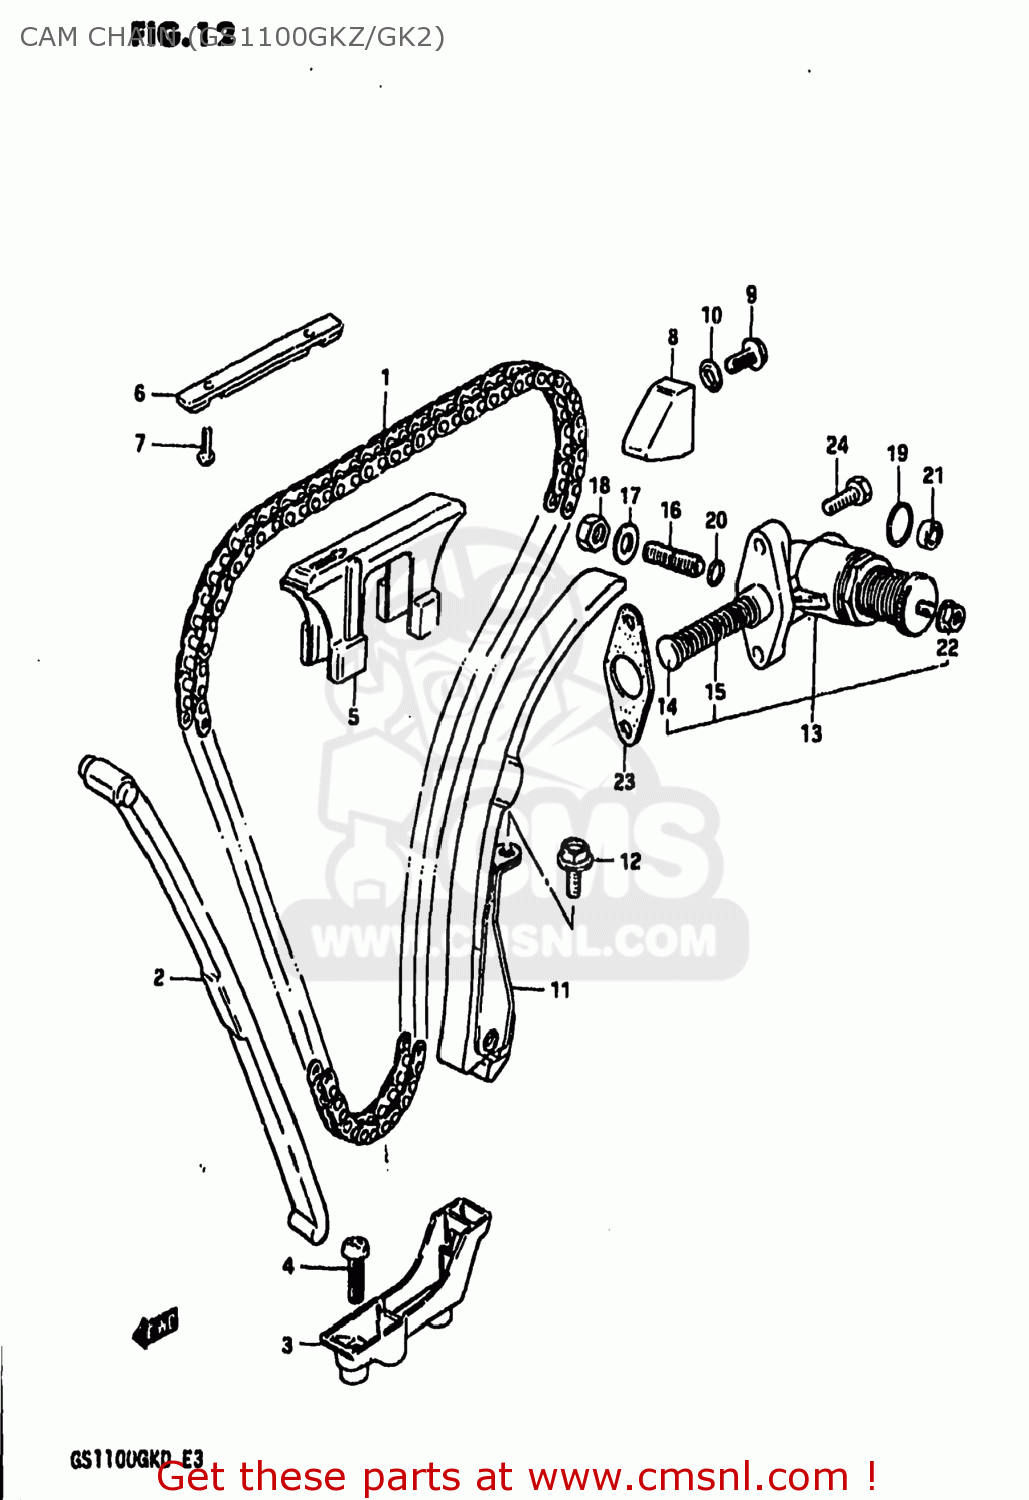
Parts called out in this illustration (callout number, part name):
1	CHAIN,CAMSHAFT DRIVE
2	GUIDE,CAM CHAIN NO.1
3	HOLDER,CAM CHAIN GUIDE
4	SCREW
5	GUIDE,CAM CHAIN NO.2
6	GUIDE,CAM CHAIN
7	SCREW
8	GUIDE,CAM CHAIN
9	BOLT
10	GASKET (NAS)
11	TENSIONER,CAM CHAIN
12	BOLT
13	ADJUSTER ASSEMBLY,TENSIONER
14	ROD,PUSH
15	SPRING
16	SCREW
17	WASHER
18	NUT
19	O-RING
20	O-RING
21	OIL SEAL
22	NUT
23	GASKET,TENSIONER ADJUSTER (MCA)
24	SCREW (6X25)
